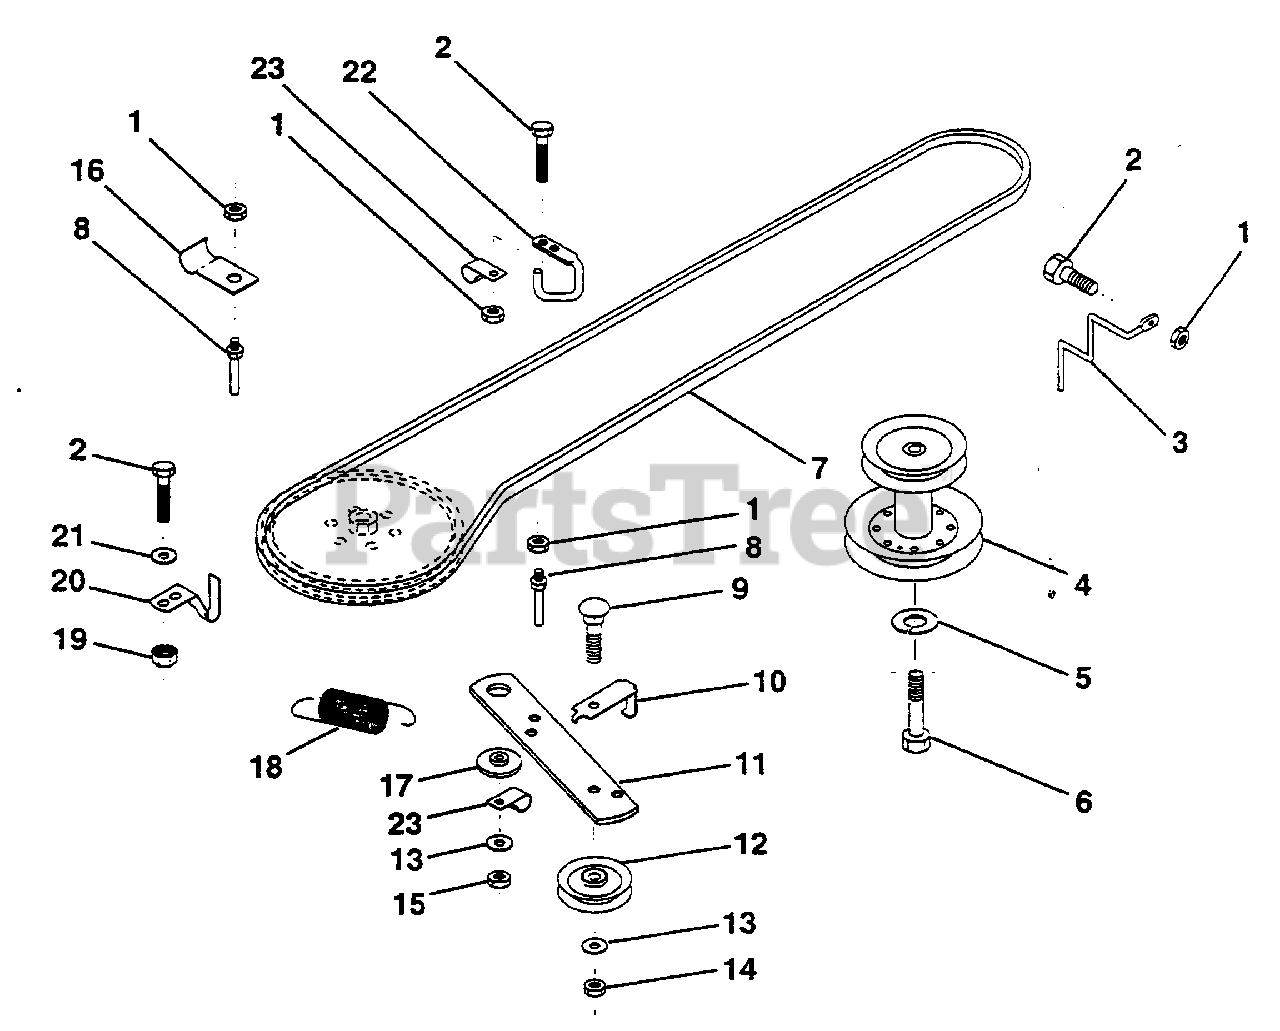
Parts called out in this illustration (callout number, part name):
1	Nut, Crownlock 5/16-18
2	Bolt, Hex Head 5/16-18 UNC x 3/4 (AYP part number)
3	Keeper, Mower Drive Belt, R.H. (AYP part number)
4	Pulley, Engine (AYP part number)
5	Washer, Lock 7/16 (AYP part number)
6	Bolt, Hex Head, Fin. 7/16-20 Grade 5 (AYP part number)
7	V-Belt, Drive (AYP part number)
8	Keeper, T/A, Ground Drive Belt (AYP part number)
9	Bolt, Carriage 3/8-16 UNC x 1-1/2 (AYP part number)
10	Keeper, Belt, Ground Drive, Idler (AYP part number)
11	Clutch Arm, Ground Drive (AYP part number)
12	Idler, Flat (AYP part number)
13	Washer 13/32 x 13/16 x 16 Gauge (AYP part number)
14	Nut, Centerlock 3/8-16 UNC (AYP part number)
15	Nut, Crownlock 3/8-16 UNC
16	Clip, Insulated (AYP part number)
17	Spacer, Retainer (AYP part number)
18	Spring, Extension (AYP part number)
19	Nut, Hex, Keps 5/16-18 UNC (AYP part number)
20	Keeper, T/A, Ground Drive Belt (AYP part number)
21	Washer 11/32 x 5/8 x 16 Gauge (AYP part number)
22	Keeper, Chassis, Ground Drive Belt (AYP part number)
23	Clip Insulated (AYP part number)
